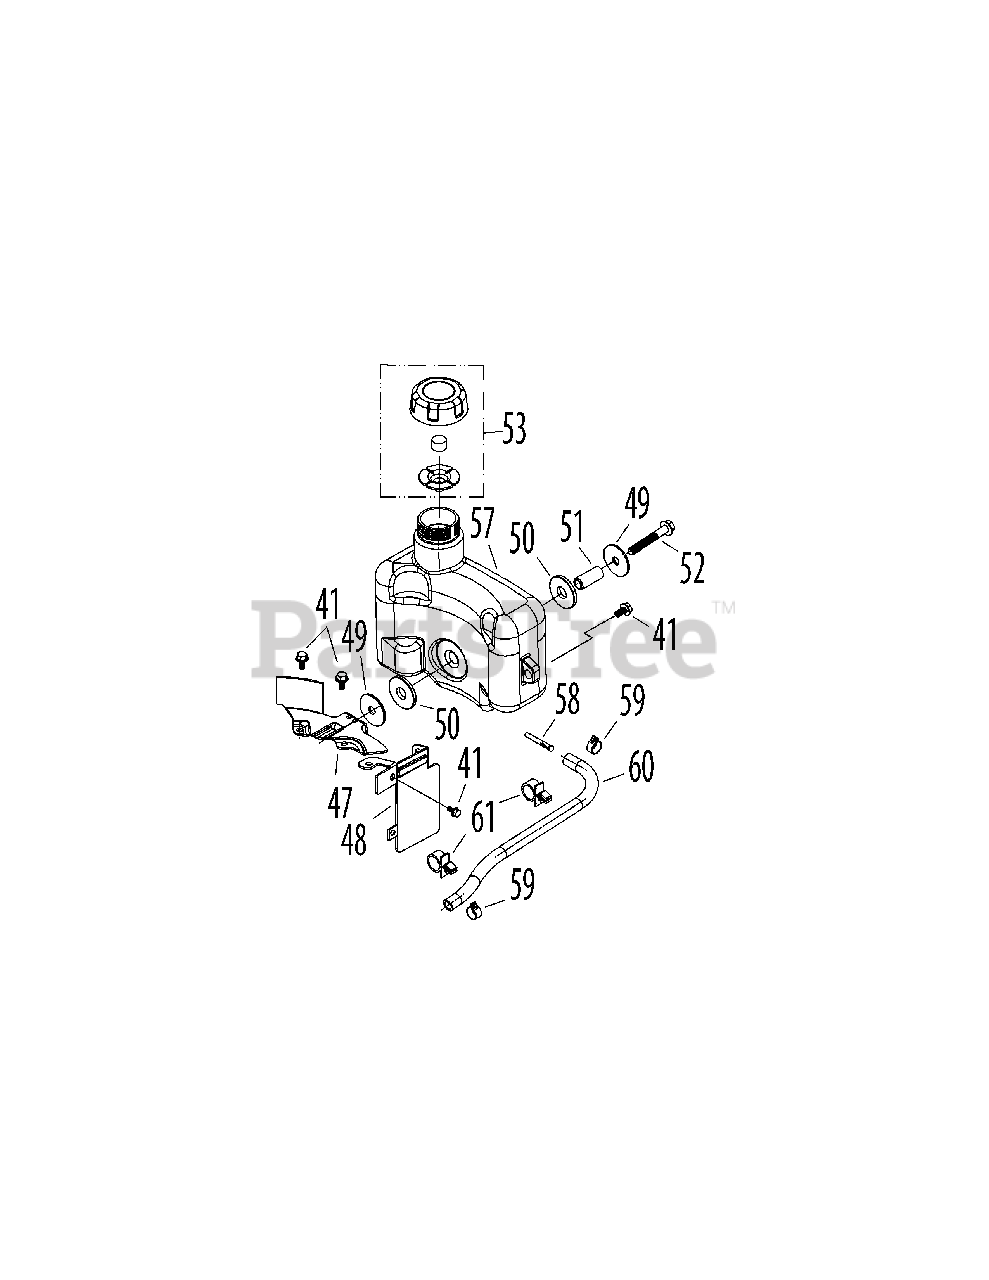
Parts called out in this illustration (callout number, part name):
41	Bolt M6×14
47	Fuel Tank Bottom Bracket
48	Tank/Label Bracket
49	Fuel Tank Washer
50	Rubber Bushing
51	Fuel Tank Bushing
52	Tank Bolt M8x50
53	Fuel Cap Assembly
57	Fuel Tank Assembly
58	Fuel Filter
59	Fuel Hose Clamp
60	Fuel Line Kit
61	Plastic Support Clamp
